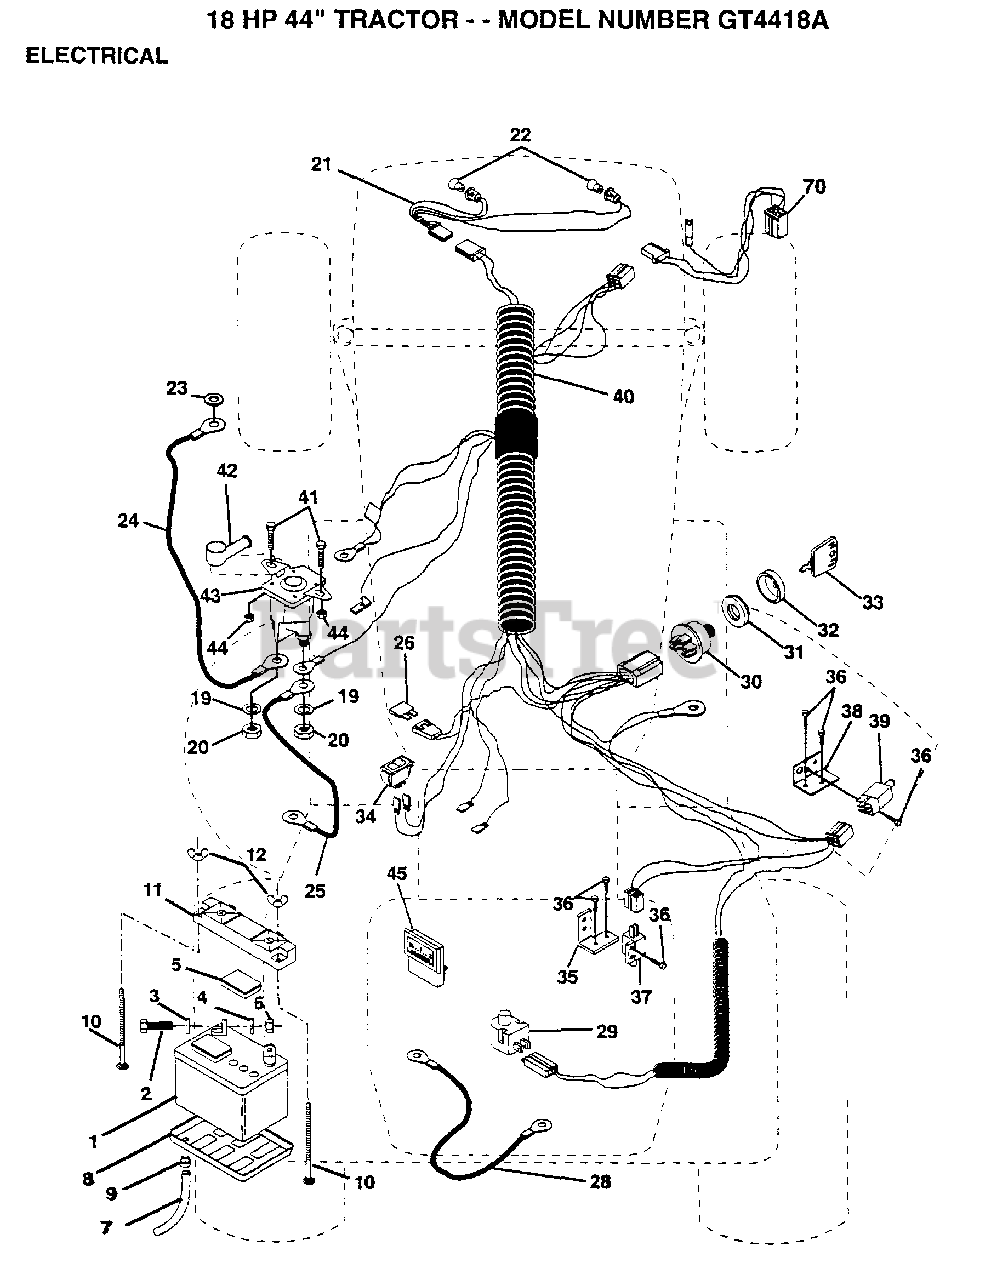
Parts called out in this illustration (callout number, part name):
2	BOLT LT
3	WASHER
4	LOCKWASHER
5	"CAP,BATTERY "
7	"DRAIN TU T, BATT"
8	"TRAY T, BATTERY"
9	HOSE CLAMP T
10	BOLT
20	NUT
21	"HARNESS,LIGHT SOC"
22	HEADLAMP BULB
23	LOCKWASHER
24	"CABLE T, BATTERY"
25	CABLE-BATTERY T
26	FUSE HYT
28	CABLE T
29	SWITCH SEAT
32	COVER KEY SWITCH
33	KEY MLD GEN DELTA
34	SWITCH LT
35	BRACKET LT
36	SCREW
37	SWITCH-INTER. GT
38	BRACKET SWITCH IN
39	SWITCH INTERLOCKT
40	HARNESS IGN DASH
41	BOLT HXHD FIN
44	NUT HXKEP 1/4X20
70	HARNESS ENGINE
